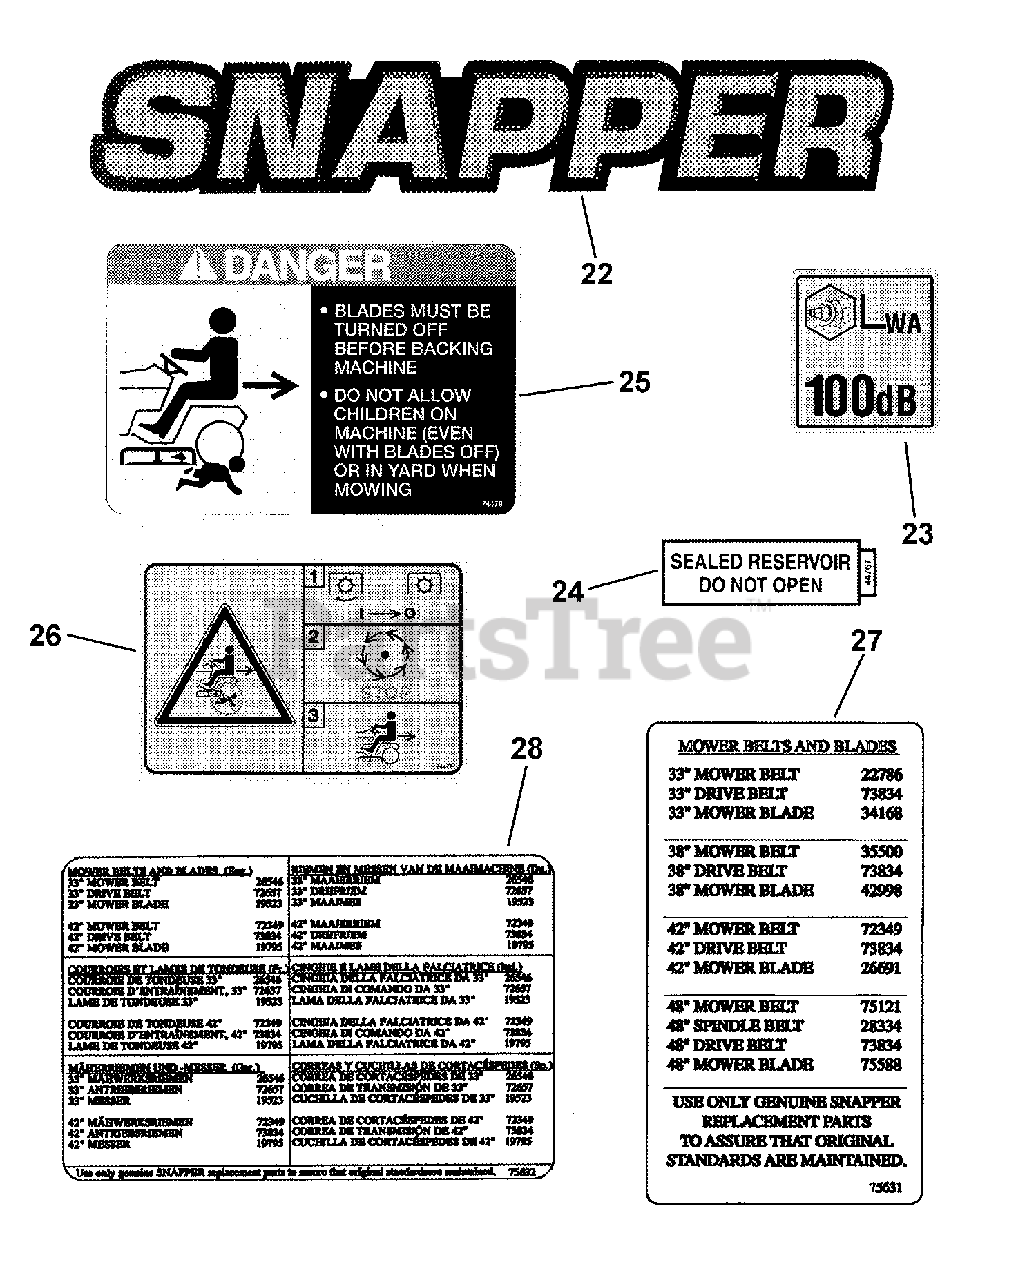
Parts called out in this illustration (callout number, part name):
22	DECAL, Snapper- Hood- 3D, Silver Letters
23	DECAL, Noise Control (Euro)
24	DECAL, Hydro Reservoir
25	DECAL, No Mow in Reverse
26	DECAL, No Mow in Reverse (Euro)
27	DECAL, Service Parts, Tractor, Domestic
28	DECAL, Service Parts, Tractor, Euro
